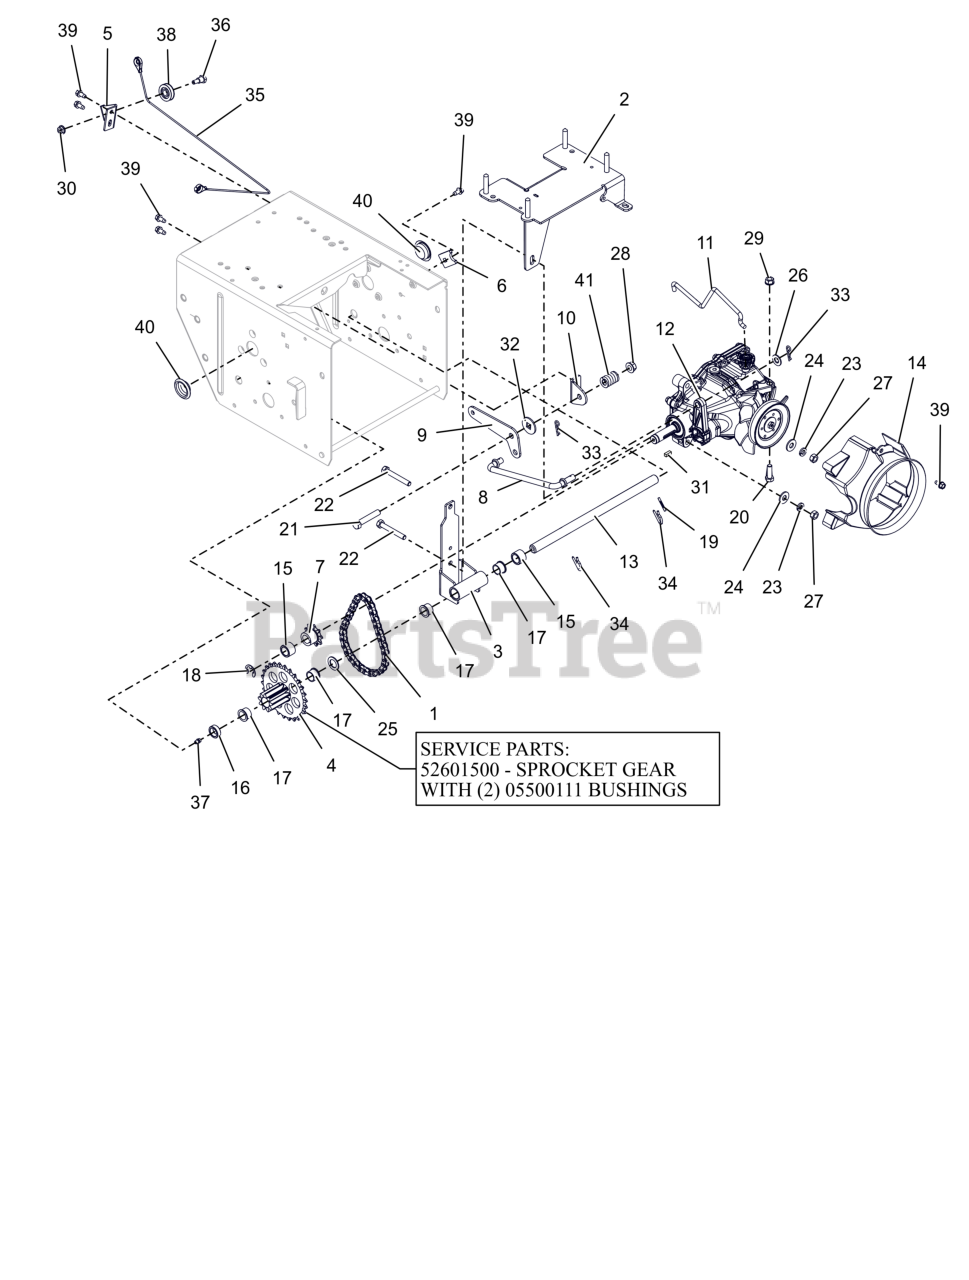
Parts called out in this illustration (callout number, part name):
1	CHAIN - #41, 32 PITCHES
2	BRACKET, HYDROSTATIC TRANS XLG
3	TRANS MOUNT, TENSIONING, WHEEL
4	PINION & SPROCKET
4	PINION & SPROCKET W/BUSHINGS
5	BRACKET, CABLE PULLEY
6	TAB, ANTI ROTATION
7	SPROCKET, PINION 9T W/KEY
8	ROD, HYDRO TRANS SHIFT
9	PIVOT, HYDRO TRANS SHIFT
10	BRACKET, HYDRO SHIFT PIVOT
11	ROD, HYDRO BYPASS
12	TRANSMISSION, HYDROSTATIC
13	SHAFT, PINION - HARDENED
14	SHROUD, HYDROGEAR RT-310
15	SPACER, .635X.880X.611
16	BSHG-SLV, .635X.880X.305
17	BSHG-FLG .625X.750X.500X.875
18	RG-RTNG-EXT .625X.042
19	@PIN-GRV .125X1.00 TP E ALLOY
20	BLT,HEX .31-18X1.00 G5 ZCC
21	BLT,HEX .38-16X2.00 G5 ZCC
22	BLT, HEX .31-18X2.25 G5 ZCC
23	WSHR, LK-HVY .312X.097 ZCC
24	WSHR,FLT .375X.875X.083 ZCC
25	WSHR, FLT .630X1.005X.062 ZCC
26	WSHR,FLT .406X.812X.065 ZCC
27	NUT, HEX .312-18 ZCC
28	NUT-LK-TOP-FLG .38-16 ZC120
29	NUT-LK-TOP-FLG .312-18 GF ZCC
30	NUT-LK-TOP-FLG .250-20 GF ZCC
31	KEY-SQ .187 X .50 X .187
32	FRICTION WASHER
33	PIN, HAIR #213 .08X1.19 ZCC
34	PIN, SPRING CLIP
35	CABLE, TRACTION, HYDRO PRO
36	BOLT, SHLDR -.375 X .375 X .25-20
37	ZERK,FITTING .25X.125 DRIVE IN
38	PULLEY, CABLE
39	SCR-TAP .25-20X.50 HWH ZCC
40	PLUG, HOLE - 1.125"
41	SG-COMP .187X.56X1.62
